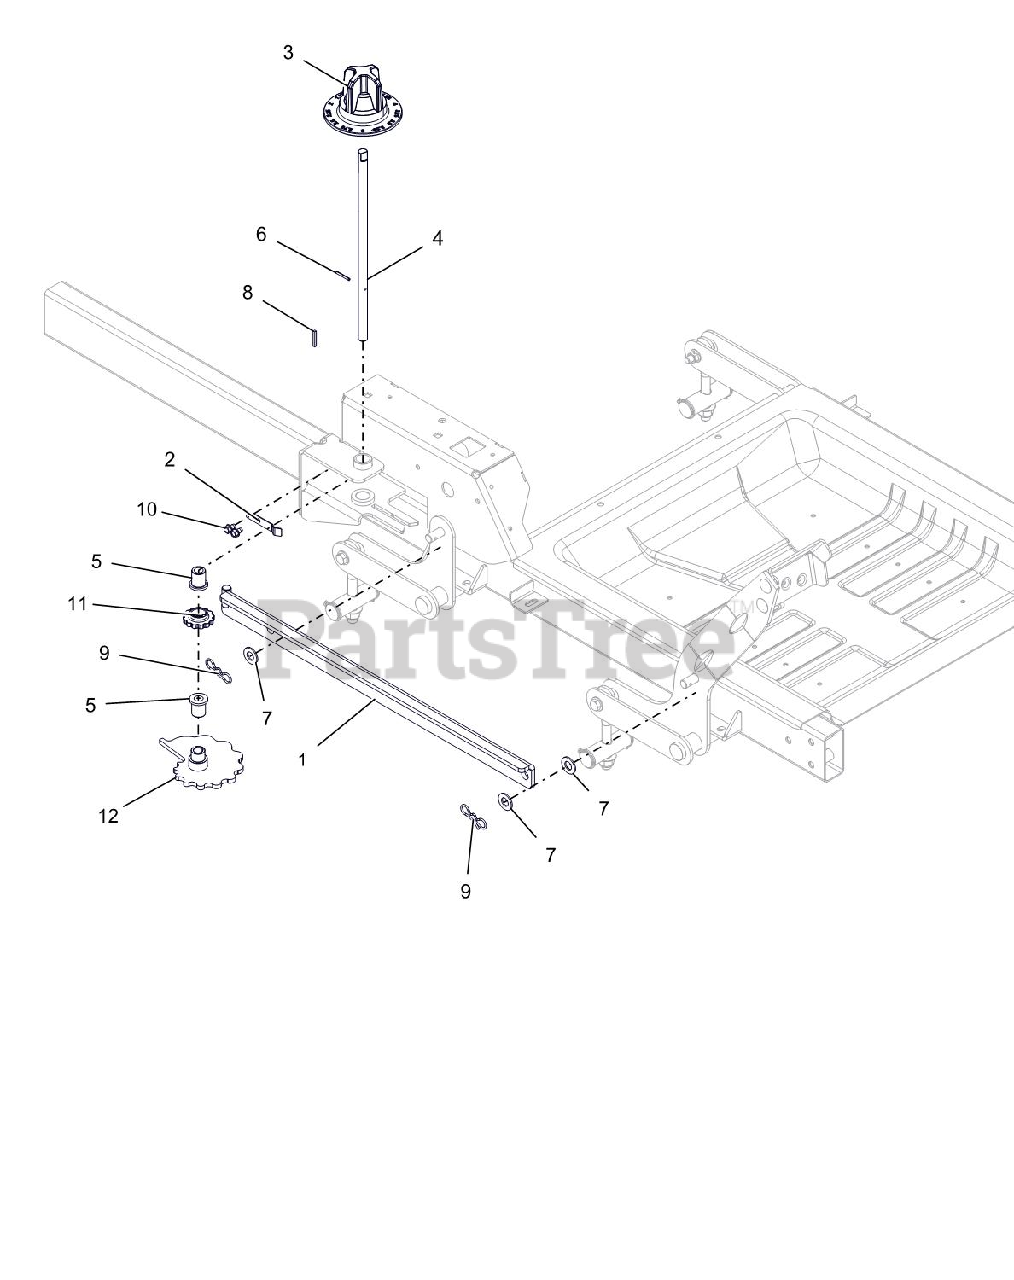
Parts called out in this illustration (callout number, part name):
1	WLDMT, HOC LINK
2	ARM, HOC DETENT
3	KNOB, HOC DIAL
4	SHAFT, HOC CAM IKON
5	BSHG-FLG, .503X.750X.875X1.00
6	PIN-ROLL .125X1.00
7	WSHR-FL-NYL .518X1.000X.080
8	KEY, 1/8 X 1/8 X 1.0
9	PIN,BOW TIE LOCKING .091X1.875
10	@SCR-TAP .25-20X.37 HWH YWZ TR
11	GEAR, HOC INDEX
12	WLDMT, HOC CAM
